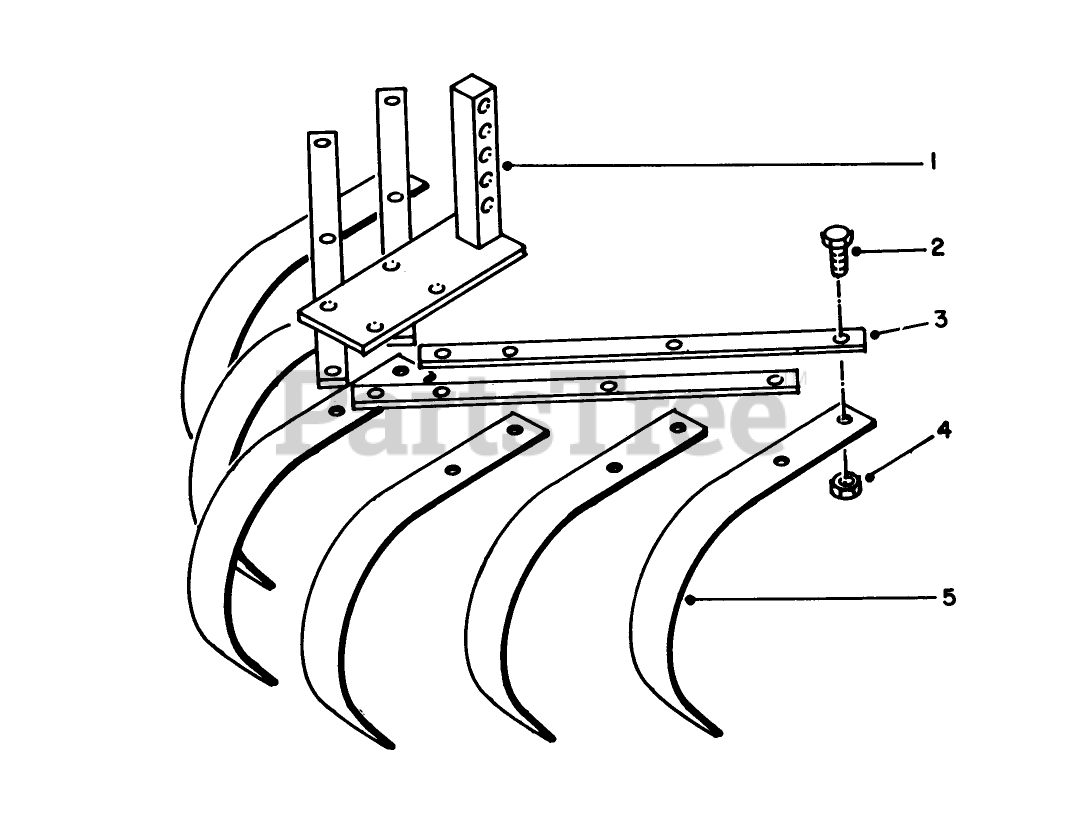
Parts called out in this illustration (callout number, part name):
1	Hitch
2	SCREW-HH
3	Attachment Bar
4	NUT-LOCK, CONE
5	Spring Tooth
